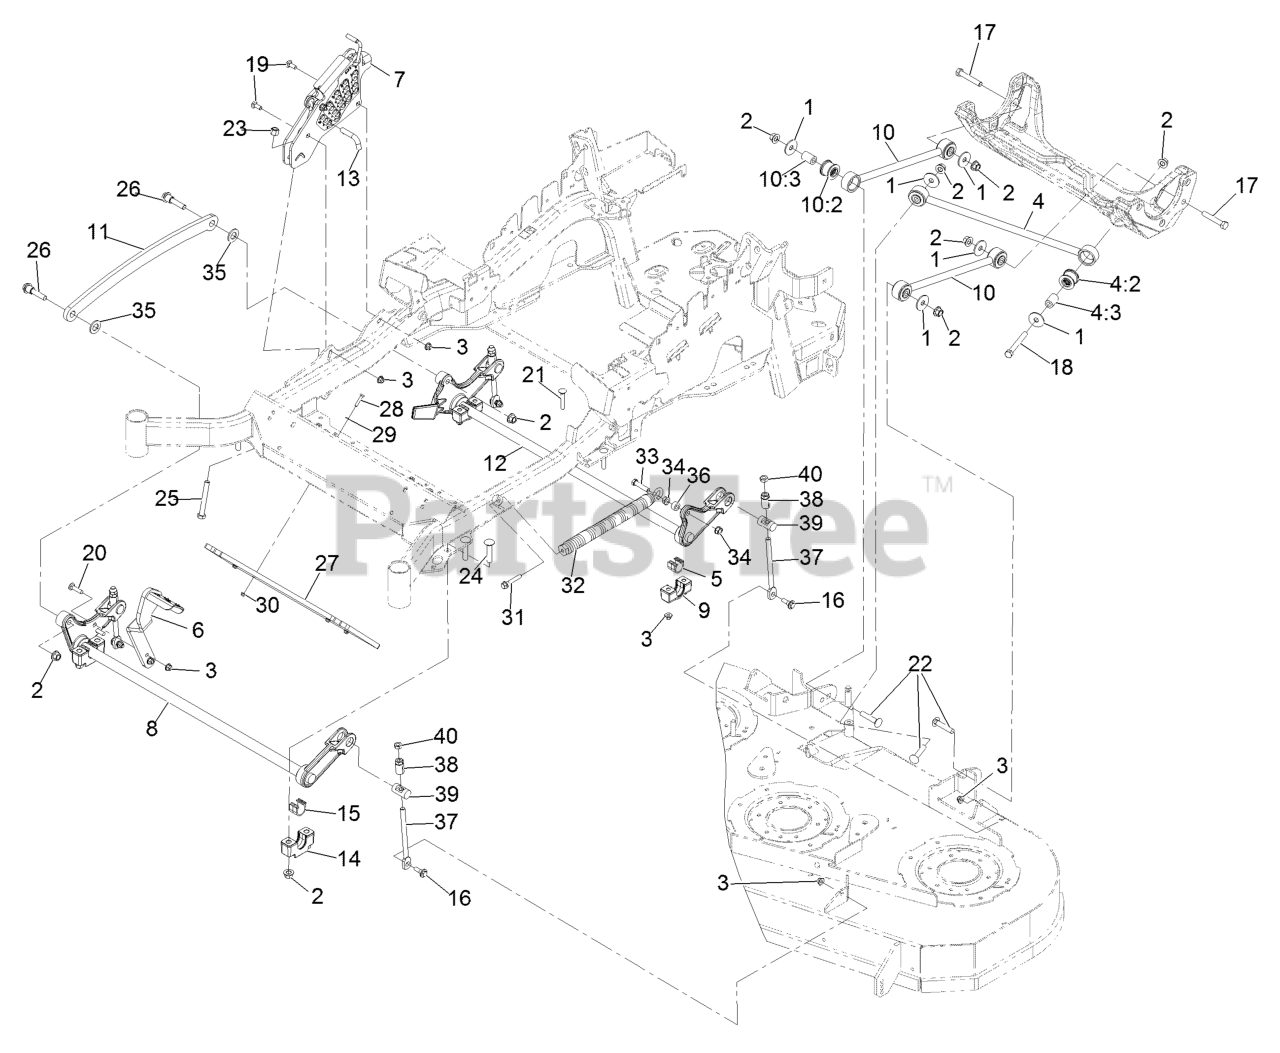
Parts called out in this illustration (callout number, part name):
1	WASHER-THRUST
2	Nut-Lock 1/2-13
3	NUT-HF, NI
4	PANHARD ROD ASM
4:2	BUSHING-SUSPENSION, RUBBER
5	BEARING-CROSS SHAFT, REAR
6	LEVER-FOOT
7	HOC ASM
8	DECKLIFT-FRONT
9	SUPPORT-CROSS SHAFT, BEARING REAR
10	DECK STRUT ASM
10:2	BUSHING-SUSPENSION, RUBBER
11	LINK-LIFT, DECK
12	LIFT-DECK, REAR
13	PIN-HOC
14	SUPPORT-CROSS SHAFT, BEARING
15	BEARING-CROSS SHAFT, FRON
16	SCREW-SHOULDER, HHF
17	SCREW-HH
18	SCREW-HH
19	BOLT-CARR
20	SCREW-CARR
21	Bolt-Carriage 3/8-16 X 2 1/4
22	SCREW-CARR
23	NUT-LOCK, NI
24	Bolt-Carriage 1/2-13 X 2 1/2 Spl Neck
25	BOLT-TAP
26	SCREW-HHF, SHOULDER
27	WEIGHT-TOE BOARD
28	SCREW-HH
29	WASHER-FLAT
31	BOLT-SHOULDER
32	SPRING-EXTENSION
33	SCREW-HH
35	WASHER-FLAT
37	LINK-ADJUSTER, DECK LIFT
38	ADJUSTER-LIFT, DECK
39	TRUNNION
40	NUT-JAM
